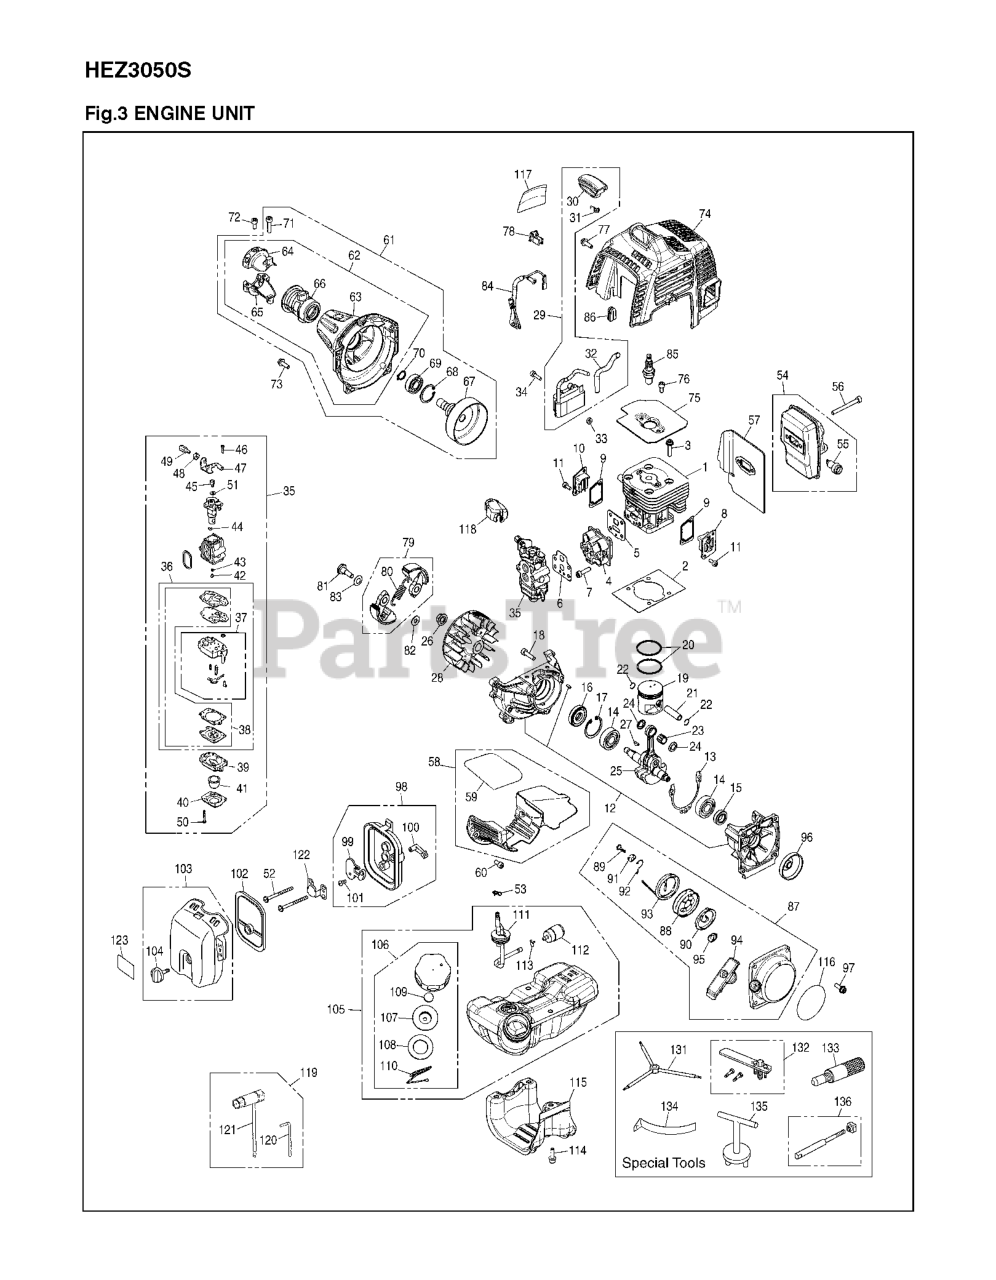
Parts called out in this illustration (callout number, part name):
1	CYLINDER
2	GASKET BASE
3	BOLT
4	INSULATOR
5	GASKET, INSULATOR
6	GASKET, CARB (RPLS T155113131)
7	BOLT, TORX
8	COVER, TRS
9	GASKET, TR
10	COVER,TRF (RPLS 848F6012D1)
11	BOLT
12	CRANKCASE-C
13	GASKET CASE
14	BEARING
20	RING
21	PIN
25	CRANKSHAFT-C
26	NUT
27	KEY
29	COIL-A
31	SPRING
33	SPACER
35	CARBURETOR ASSY
36	REBUILD KIT
38	GASKET KIT
39	BODY
40	1OVER
41	PUMP
44	RING
45	SWIVEL
46	SCREW
47	BRACKET
48	NUT
49	ADJUSTER
51	WASHER
52	BOLT TORX
53	CLIP
54	MUFFLER ASSY
55	ARRESTER
57	GASKET
58	PLATE-A
61	HOUSING ASSY
62	HOUSING COMP.
64	BRACKET (A) (RPLS T170031211)
65	BRACKET (B)
67	DRUM (RPLS 481031120-22)
69	BEARING
74	COVER.ENGINE
75	RP_PLATE
79	SHOE-C
83	WASHER
84	CORD-COMP
85	PLUG CMR7H
87	RECOIL ASSY
90	SPRING, SPIRAL
91	COLLAR
92	SWING ARM
95	PLATE.STOPPER
98	CLEANER BODY ASSY
99	PLATE, CHOKE
101	SCREW
102	ELEMENT
103	%CLEANER COVER ASSY
104	Cleaner Knob
107	HOLDER-A
111	PIPE-C
112	FILTER
113	CLIP
115	GUARD, TANK
116	LABEL, RECOIL
119	TOOL SET (RPLS 848-8UD-0120)
121	SOCKET
131	WRENCH
132	FLYWHEEL PULLER
133	STOPPER
134	GAUGE
135	PULLER
136	ROD-A
